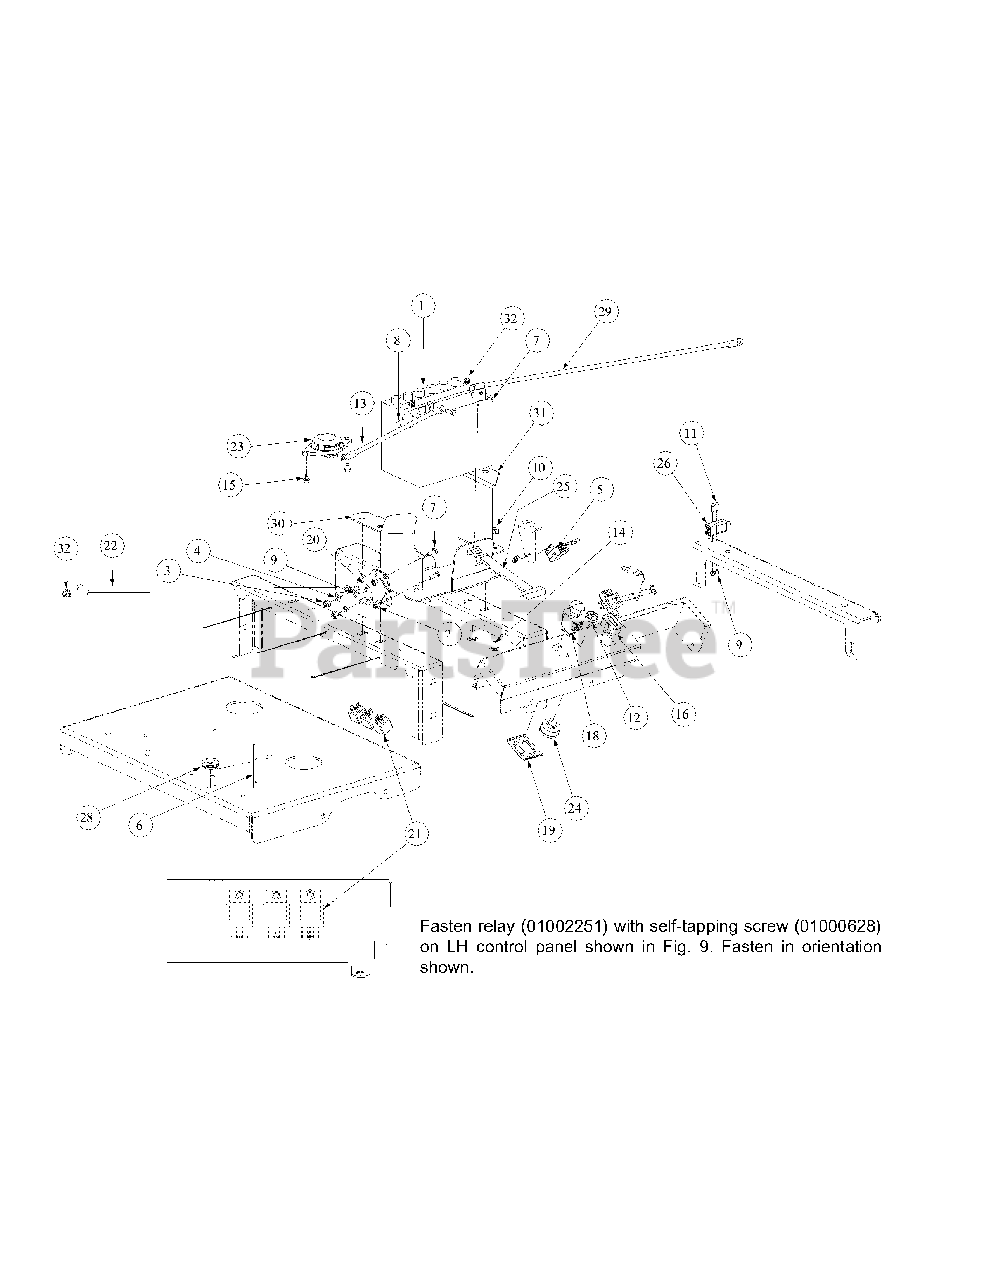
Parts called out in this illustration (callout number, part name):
2	Nut, Lock, Nylon Insert, 1/4-20
3	Nylock Nut, 5/16-18
4	Lock Washer, 5/16
5	Switch, Safety
6	Tie, Cable, 3/16 x .05 x 7.4"
7	Screw, Hex, Cap, 1/4-20 x .75
8	Boot, 1" OD Rubber Battery-PST, Red
9	Nut, Lock, Nylon Insert, #10-32
10	Nut, Hex, Flange Lock, 3/8-16
11	Screw, Phillips Head, Machine, 10-32 x 5/8
12	Nut, W/Cap, 5/8-32 Ignition
13	Cable, Battery, Red, 15"
14	Carriage Bolt, 3/8-16 x .75 LG.
15	Screw, TT, 1/4-20 x .500, Hex Index Washer
16	Meter, Hour
18	Switch, Electric, PTO
19	Bracket, PTO Switch Retainer
20	Solenoid Magnetic Switch
21	Relay, 12V 40A
22	Cable, Battery Red, 32"
23	Switch, Seat
24	Switch, Ignition, 6 Pin
24	Key, Ignition
25	Strap, Battery
26	Switch, Plunger
28	Grommet, .75 ID
29	Cable, Battery Black, 24"
30	Mount Bracket, Battery
31	Mount Bracket, Battery
32	Nut, 1/4-20, Hex Flange Lock Nut
